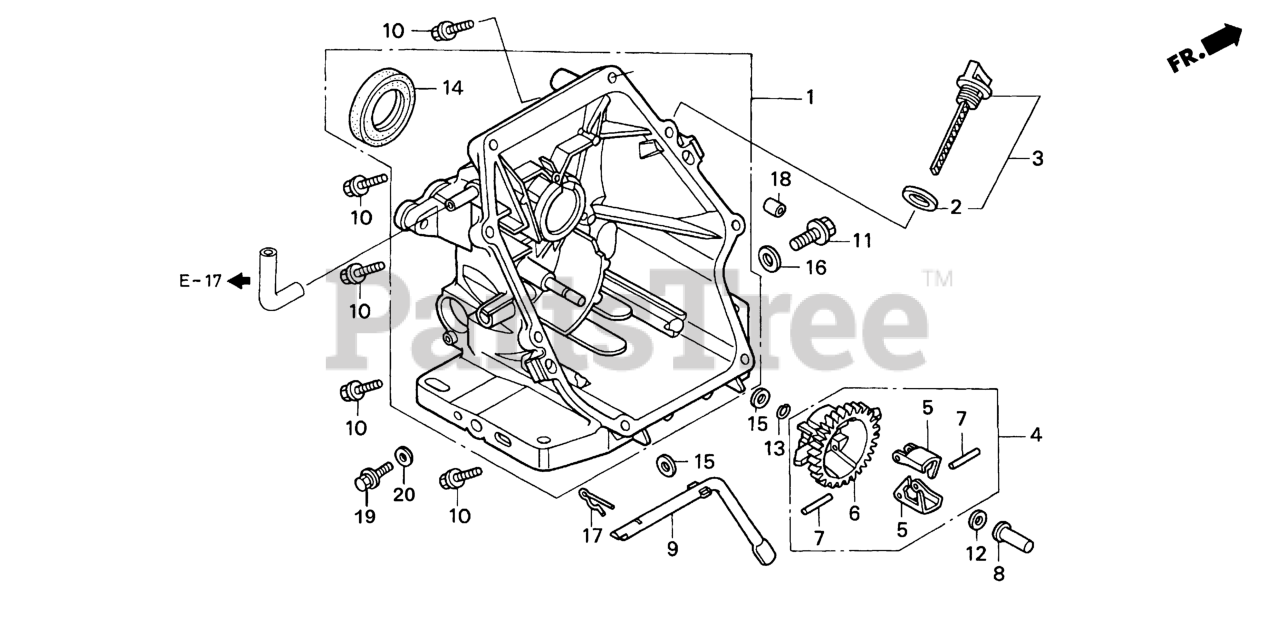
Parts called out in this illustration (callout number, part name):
1	COVER ASSY., CRANKCASE
2	GASKET, OIL FILLER CAP
3	GAUGE ASSY., OIL LEVEL
4	GOVERNOR ASSY.
5	WEIGHT, GOVERNOR
6	HOLDER, GOVERNOR WEIGHT
7	PIN, GOVERNOR WEIGHT
8	SLIDER, GOVERNOR
8	ARRESTER, SPARK (TO 1207644)
9	SHAFT, GOVERNOR ARM
9	PLATE, ARRESTER NUMBER (TO INSTALL OPTIONAL SPARK ARRESTER)
10	BOLT, FLANGE (6X25) Use up to Engine SN 2056819.
10	SCREW, TAPPING (4X6) (TO INSTALL OPTIONAL SPARK ARRESTER)
11	BOLT, DRAIN PLUG
12	WASHER, THRUST (6MM)
13	CLIP, GOVERNOR HOLDER
14	OIL SEAL (28X41.25X6)
15	WASHER, PLAIN (6MM)
16	WASHER, DRAIN PLUG (12MM)
17	PIN, LOCK (8MM)
18	PIN, DOWEL (8X20)
19	BOLT, DRAIN PLUG
20	WASHER, DRAIN PLUG (12MM)
